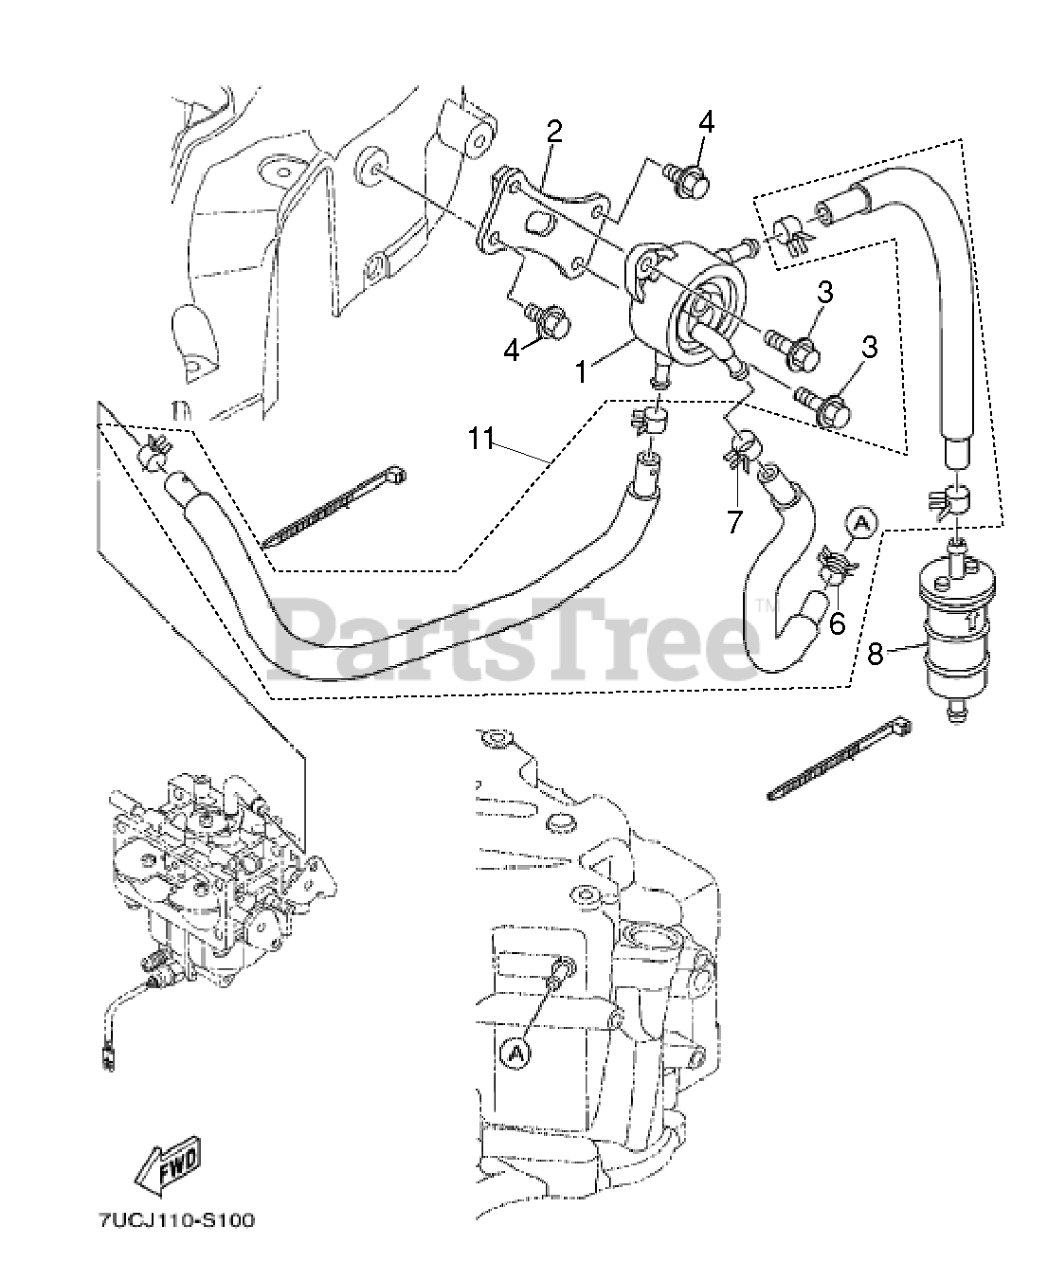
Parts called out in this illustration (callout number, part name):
1	FUEL PUMP ASSY YAMAHA PN: 7VV-
2	BRACKET FUEL PUMP 2 YAMAHA PN:
3	BOLT YAMAHA PN: 95822-06016
4	BOLT YAMAHA PN: 95822-06010
6	CLIP SERVICE KIT X10
7	CLIP SERVICE KIT X10
8	FUEL FILTER YAMAHA PN: 7UD-F4
11	HOSE KIT FUEL PUMP HOSE KIT
